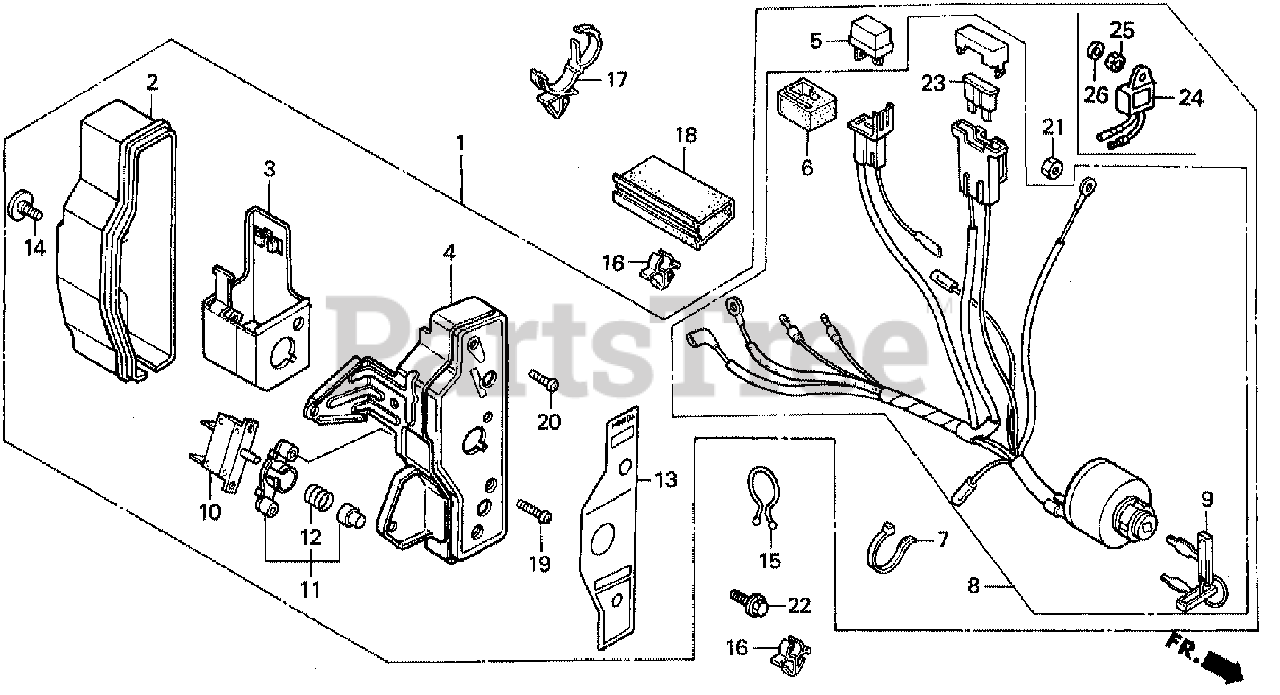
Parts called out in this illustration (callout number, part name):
1	BOX ASSY., CONTROL *R8* (EXTERNAL-ALERT) (BRIGHT RED)
2	CASE, CONTROL
3	BRACKET, CASE MOUNTING
4	PANEL, CONTROL *NH1* (BLACK)
4	PANEL, CONTROL *R8* (BRIGHT RED)
5	RECTIFIER ASSY., SILICON (STANLEY)
6	SUSPENSION, CONNECTOR
7	BAND
8	SWITCH ASSY., COMBINATION
9	KEY
10	PROTECTOR, CIRCUIT (1.0A)
11	LENS ASSY., PROTECTOR
12	SPRING, COIL
13	PANEL, CONTROL BOX (EXTERNAL)
14	SCREW, SPECIAL (6X12)
15	CLIP, PURSE LOCK
16	CLIP, CORD
17	STRAP, WIRE HARNESS (25MM) (BLACK)
18	TUBE, FASTENER (30)
19	SCREW, PAN (3X12)
20	SCREW, PAN (4X12)
21	NUT, HEX. (4MM)
22	BOLT, FLANGE (6X10)
23	FUSE, BLADE (5A)
24	ALERT UNIT, OIL
25	WASHER, PLAIN (4MM)
26	WASHER, SPRING (4MM)
